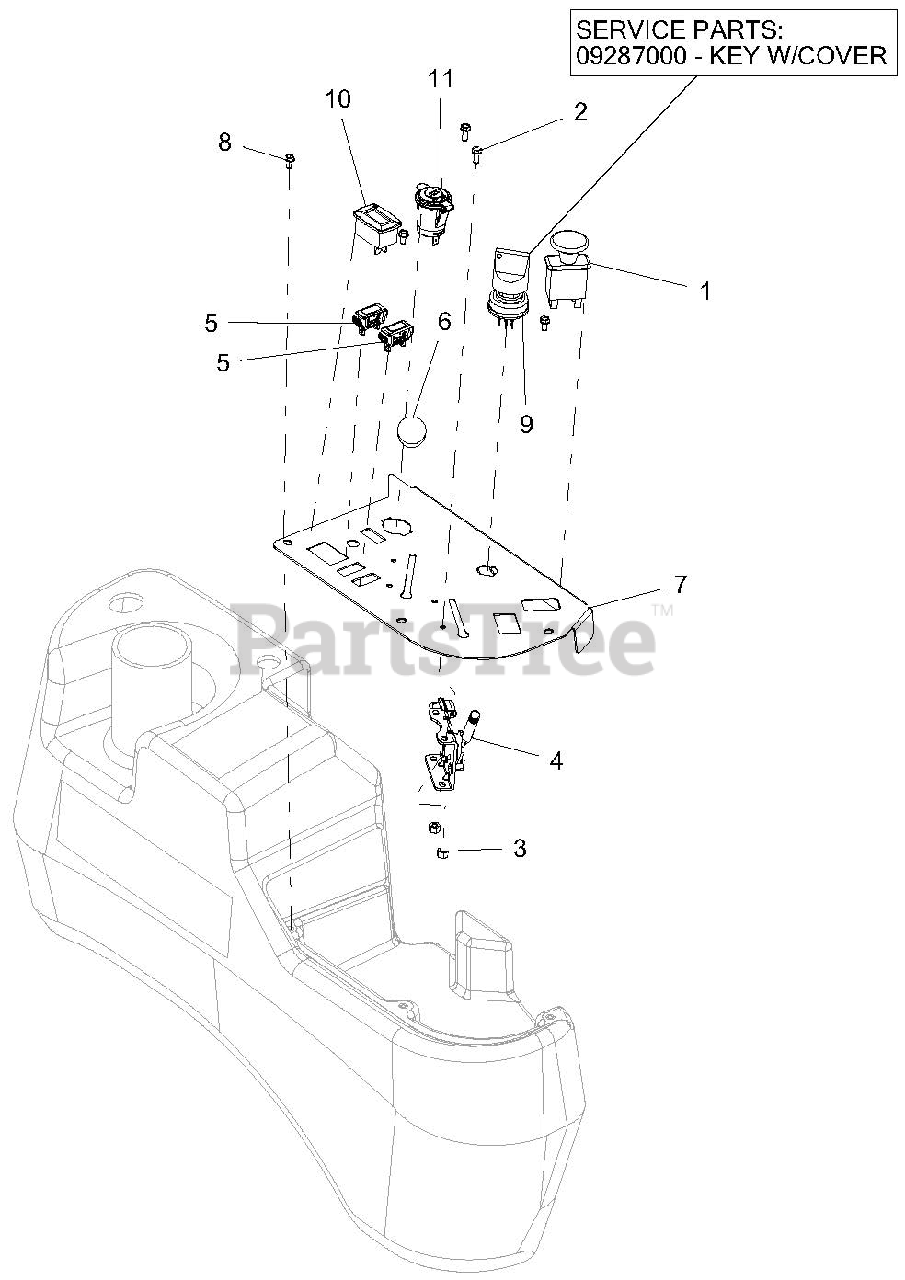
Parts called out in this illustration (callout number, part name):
1	SWITCH, CLUTCH
2	@SCR-MCH 10-24X.50 HWH YWZC
3	NUT-LK-NYL #10-24 YWZC
4	CABLE, PRO-CONTROL THROTTLE
5	LIGHT, INDICATOR
6	KNOB, CONTROL BLACK .38-16X.50
7	PANEL, CONTROL
8	SCR-MCH 10-24X.38 HWHSTAINLESS
9	SWITCH, IGNITION
9	KEY W/COVER
10	METER, HOUR W/MAINTENANCE
11	PORT, 12 VOLT POWER
